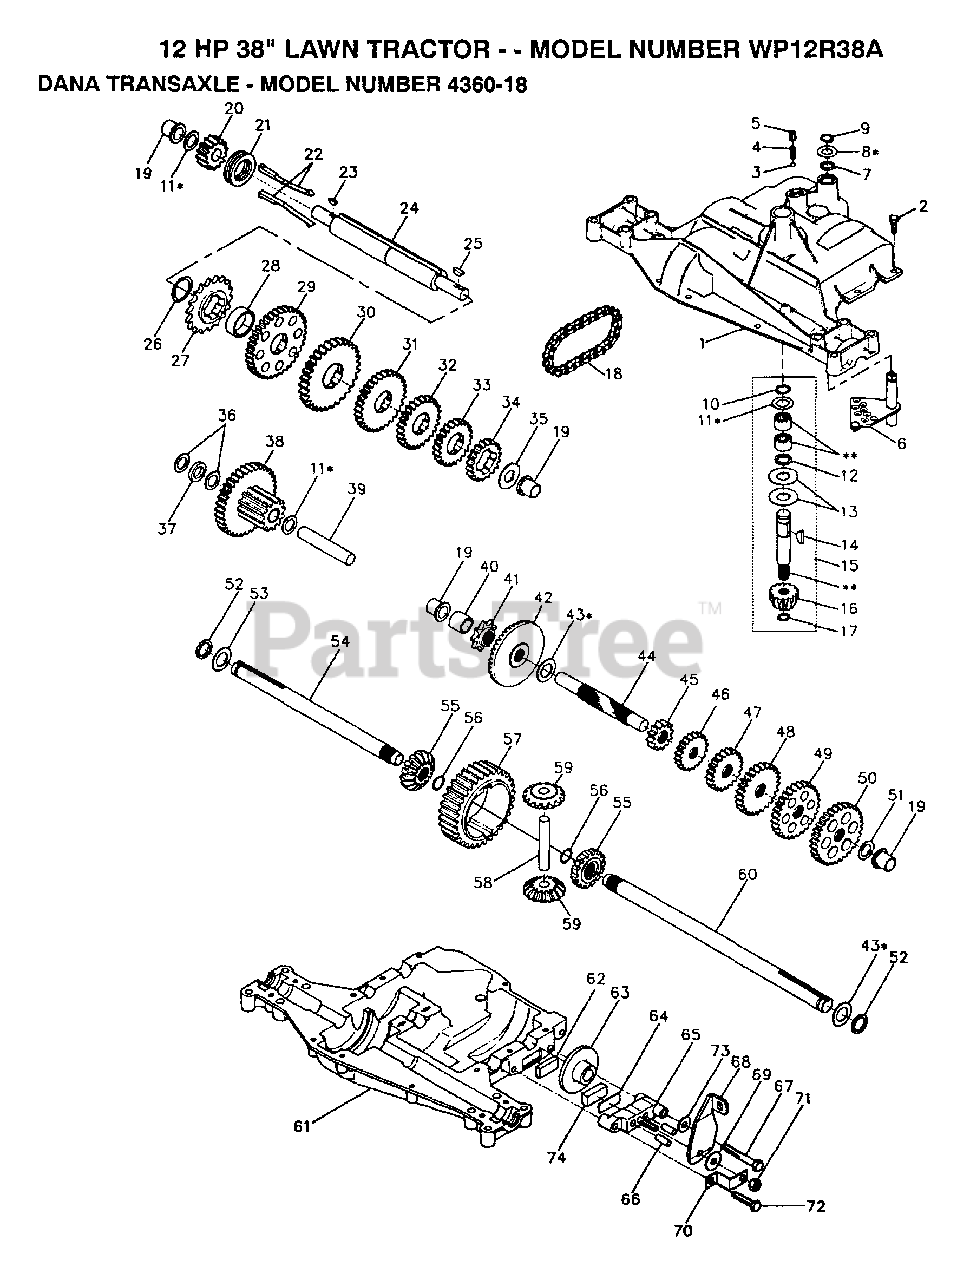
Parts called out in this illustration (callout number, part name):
1	HOUSING UPPER
3	BALL DETENT
4	SPRING, DETENT
5	SCREW, SET
6	ASSY SHIFTER
8	WASHER PLAIN
9	RING RETAINING
10	RING RETAINING
11	WASHER PLAIN
13	WASHER, PLAIN .632 X 1.38 X .046
14	KEY WOODRUFF #9
15	ASSY KIT INPUT SHAFT
16	PINION, BEVEL, 14 TEETH
17	RING, RETAINING
18	CHAIN, 24 PITCHES
19	BEARING, FLANGE
20	GEAR SPUR, 14 TEETH
21	COLLAR CLUTCH
22	KEY CLUTCH
23	KEY WOODRUFF #3
24	SHAFT INTERMEDIATE
25	KEY, WOODRUFF, #61
26	RING, RETAINING
27	SPROCKET, 18 TEETH
29	GEAR, SPUR, 37 TEETH
30	GEAR, SPUR, 35 TEETH
31	GEAR, SPUR, 30 TEETH
32	GEAR, SPUR, 25 TEETH
33	GEAR, SPUR, 22 TEETH
35	WASHER, PLAIN .640 X 1.37 X .061
36	WASHER, PLAIN .632 X 1.00 X .026
37	SPACER .630 X 1.00 X .169
38	ASSY GEAR COMB 12&35 TEETH
39	SHAFT IDLER
40	SPACER .635 X .875 X .755
41	SPROCKET, 9 TEETH
42	GEAR, BEVEL, 42 TEETH
43	WASHER PLAIN
44	SHAFT, DRIVE
45	GEAR, SPUR, 12 TEETH
46	GEAR SPUR, 15 TEETH
47	GEAR, SPUR, 20 TEETH
48	GEAR, SPUR, 25 TEETH
49	GEAR, SPUR, 28 TEETH
50	GEAR, SPUR, 31 TEETH
51	WASHER, PLAIN .632 X 1.00 X .060
53	WASHER PLAIN
54	AXLE LEFT HAND
55	GEAR, MITER, 15 TEETH
56	RING, RETAINING
57	GEAR, SPUR, 32 TEETH
58	SHAFT, CROSS
59	GEAR, MITER, 15 TEETH
60	AXLE RIGHT HAND
61	HOUSING LOWER
62	PUCK, FRICTION
63	DISC, BRAKE
65	JAW, BRAKE
66	PIN, DOWEL
67	SCREW TAPPING
68	LEVER, ACTUATING
69	WASHER, PLAIN .321 X 1.00 X .055
70	BRACKET, ANTI-ROTATION
71	LOCKNUT 5/16-24
72	SCREW TAPPING
73	WASHER PLAIN
74	PUCK, FRICTION
